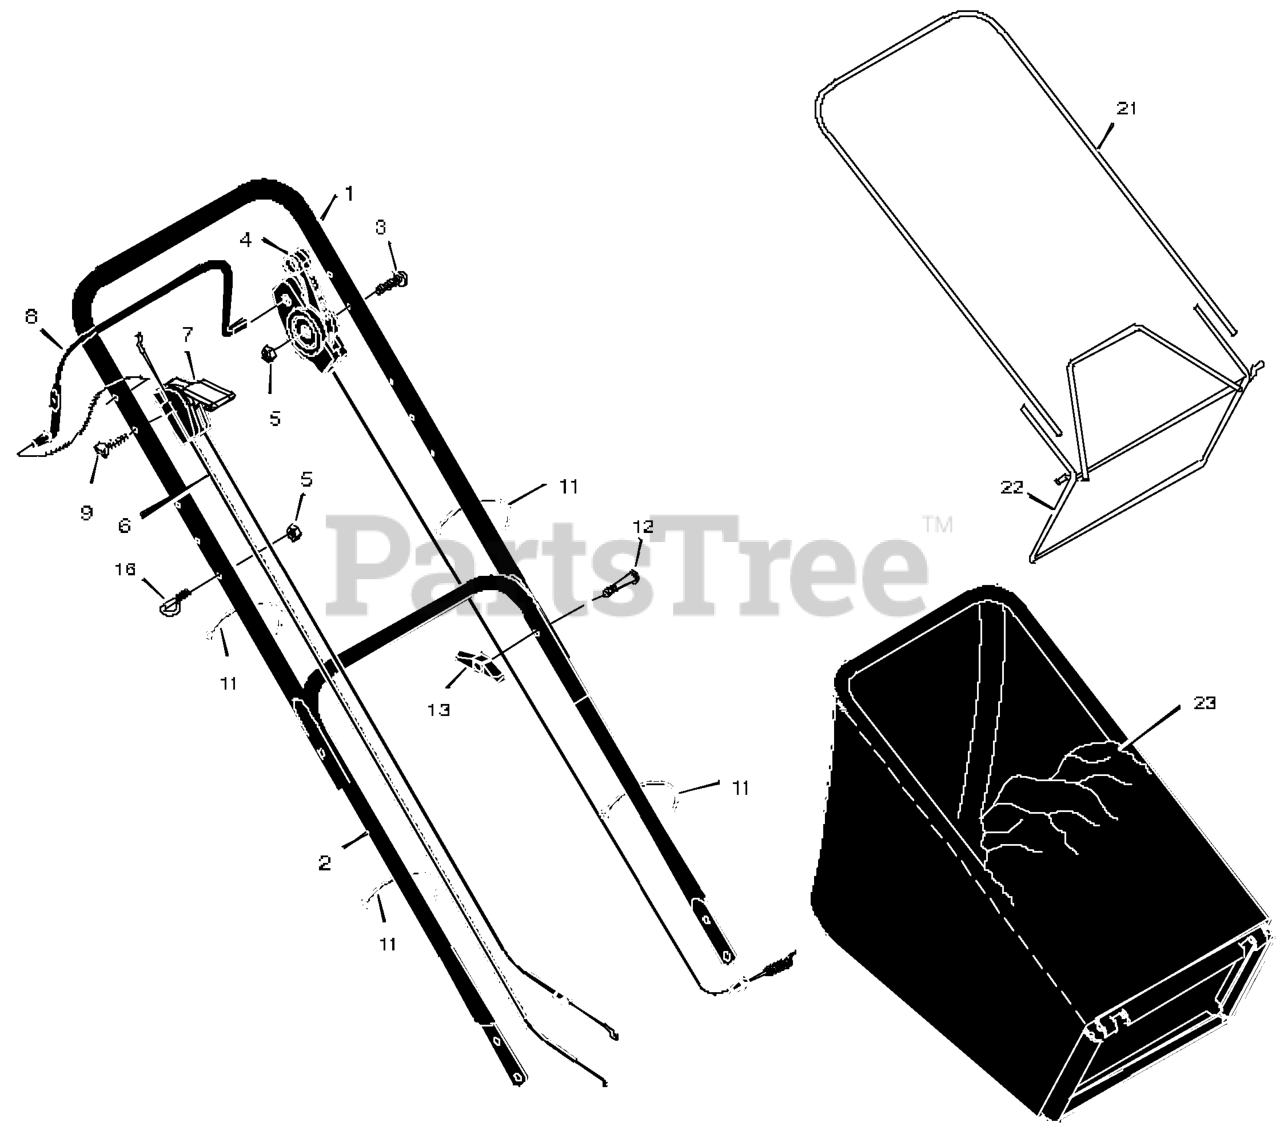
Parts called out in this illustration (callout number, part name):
1	Handle, Upper (Black)
2	Handle, Lower (Black)
4	Control, Drive
5	Locknut
6	Cable, Stop
7	Throttle Control
8	Lever, Stop
11	Fastener, Cable
13	Knob
16	GUIDE, ROPE
21	Frame, Top
22	Frame Assembly
23	Bag, Cloth
